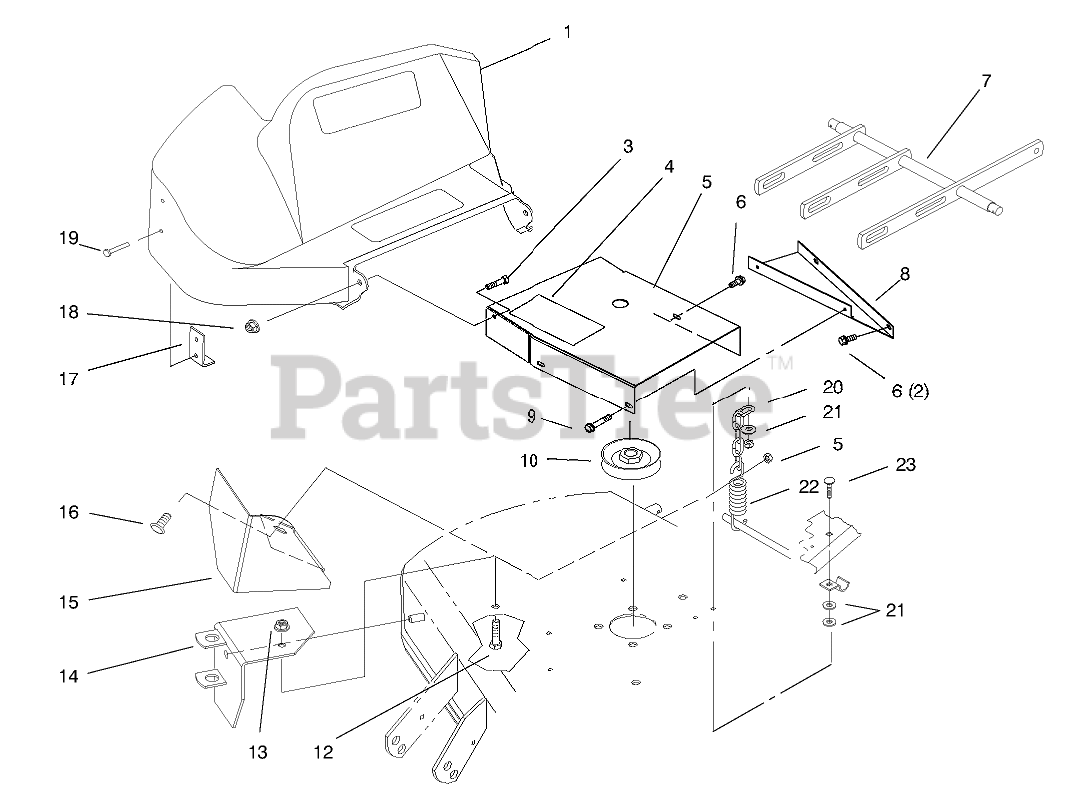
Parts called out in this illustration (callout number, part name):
1	SHIELD-BELT
3	SCREW-HH
4	DECAL-DANGER
5	Inner Shield Assembly (Incl. Ref. #4)
6	SCREW-HHF
7	Bar-Leveler
8	48" ADAPTOR SHIELD B
9	SCREW-HWH
10	PULLEY
11	NUT-LOCK, NI
12	SCREW-HH
13	NUT-HF
14	PIVOT SUPPORT ASM
15	48" DEFLECTOR B
16	SCREW-CARR
17	BRACKET-SUPPORT, SHIELD
18	NUT-LOCK, NI
19	RIVET-POP
20	CHAIN
21	WASHER-FLAT
22	SPRING-EXTENSION
23	SCREW-CARR
